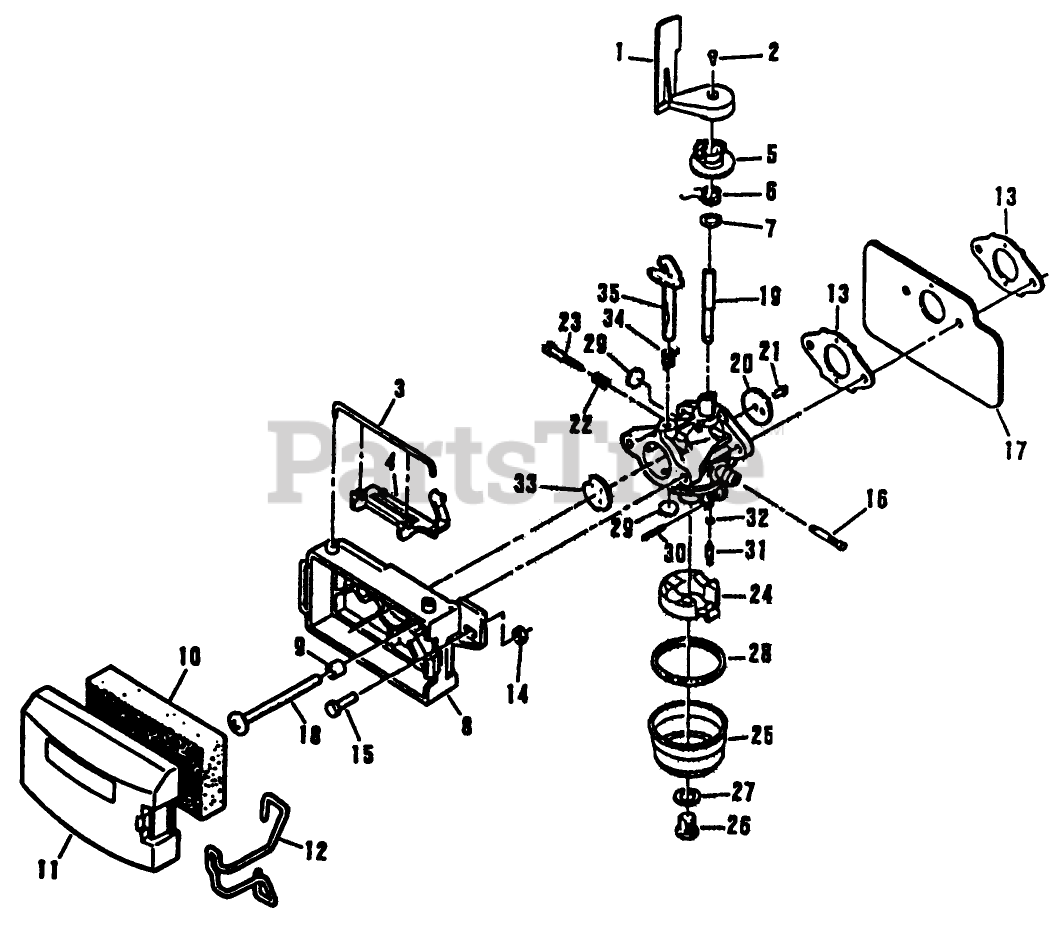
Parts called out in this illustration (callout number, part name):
1	AIR VANE F
2	SCREW F
3	RETAINER
5	COLLAR A/VAVE F
6	THROTTLE SPR E
7	WASHER VF
9	SPACER
12	RETAINER-COVER, FILTER
13	GASKET CARB S
15	SCREW
16	SCREEN FUEL PITTS
17	SHIELD, CARB F
18	SCREW
19	? Throttle Shaft
20	? Throttle Valve
21	? Screw-Throttle Valve
22	? Spring-Idle Needle
23	? Idle Needle
25	? Fuel Bowl
26	? Screw-Bowl Retainer
27	? Bowl Retainer Gasket
28	? Fuel Bowl Gasket
29	? Plug-Welch
30	? Float Shaft
31	? Inlet Needle Valve
32	? Valve Seat
33	? Choke Valve
34	? Choke Return Spring
35	? Choke Shaft
